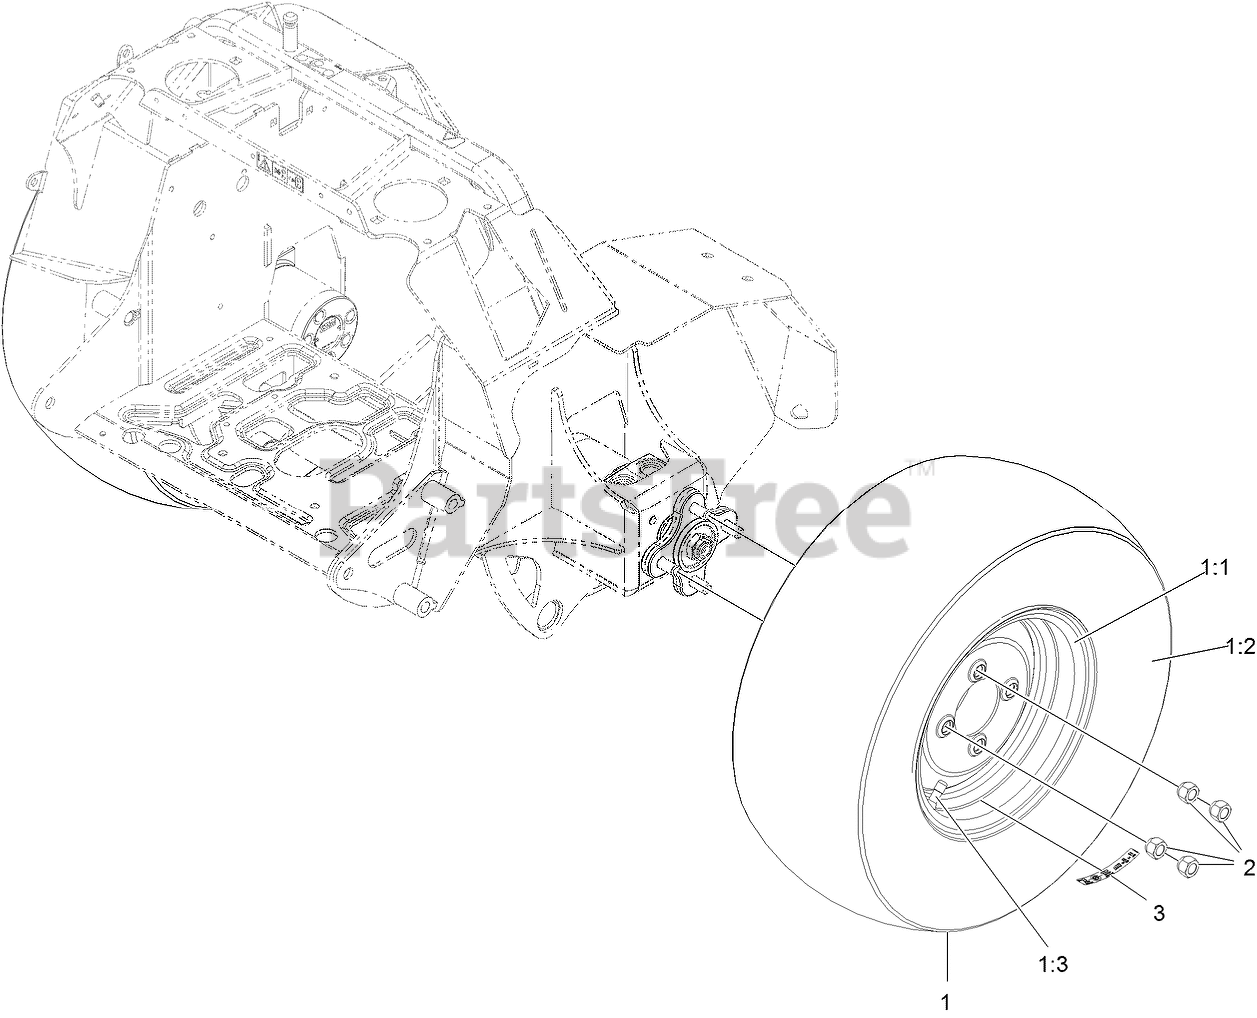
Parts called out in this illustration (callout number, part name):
1	ASM-WHL TIRE
1:1	WHEEL 10 X 6 WHT
1:2	TIRE-21X8.5-10
1:3	Stem-Valve
2	NUT-LUG
3	DECAL-TORQUE WHEEL LUG-HU
